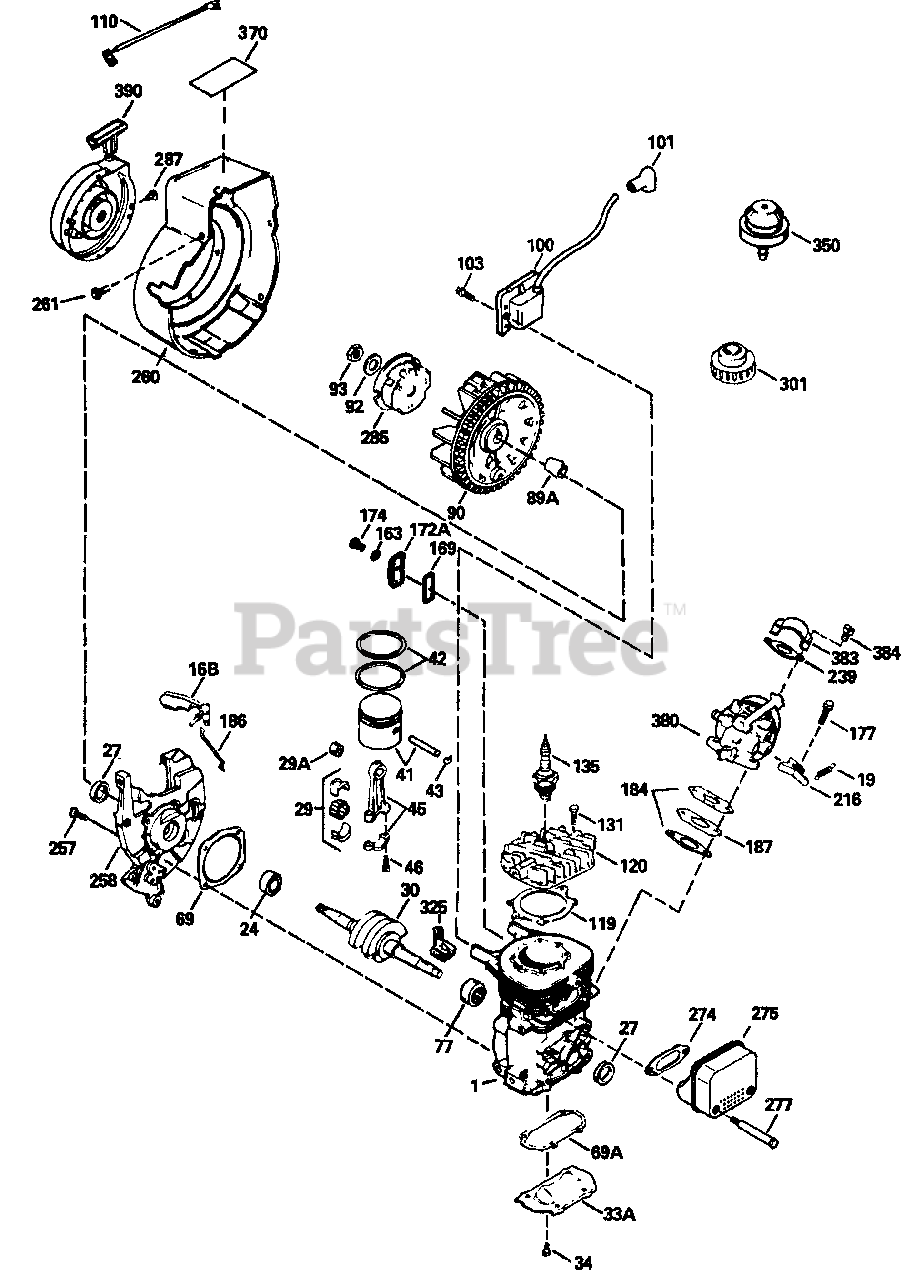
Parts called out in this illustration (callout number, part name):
1	Cylinder
19	Extension Spring
24	Ball Bearing
29	Needle Bearing & Liner Set
29A	Cartridge Bearing
30	Crankshaft
33A	Cover Plate
34	Screw, Torx T-25, 10-24 x 1/2"
41	Piston & Ring Ass'y
42	Ring Set
43	Piston Ring Retaining Ring
45	Connecting Rod Ass'y
46	Connecting Rod Bolt
69	Cylinder Cover Gasket
69A	Cover Plate Gasket
77	Cartridge Bearing
89A	Adapter Sleeve
92	Bell Washer
93	Flywheel Nut
100	Solid State Ignition
101	Spark Plug Cover
103	Screw, Torx T-15, 10-24 x 1"
110	Ground Wire
119	Cylinder Head Gasket
120	Cylinder Head
131	Screw, Torx T-30, 1/4-20 x 3/4"
135	Resistor Spark Plug
169	Cover Plate Gasket
172A	Compression Release Cover
174	Screw, Torx T-25, 10-24 x 1/2"
177	Screw, 5/32 Allen, 1/4-20 x 5/8"
184	Carburetor Gasket
186	Governor Link
216	RPM Adjuster Lever
239	Air Cleaner Gasket
257	Screw, Torx T-30, 1/4-20 x 5/8"
258	Blower Housing Base
260	Blower Housing
261	Screw, 1/4-20 x 1/2"
274	Exhaust Gasket
275	Muffler
277	Screw, 1/4-20 x 2-3/4"
285	Starter Cup
287	Screw, 8-20 x 21/64"
325	Wire Clip
350	Primer Ass'y
370	Instruction Decal
380	Carburetor
384	Screw, Torx T-25, 10-32 x 3/8"
390	Rewind Starter
